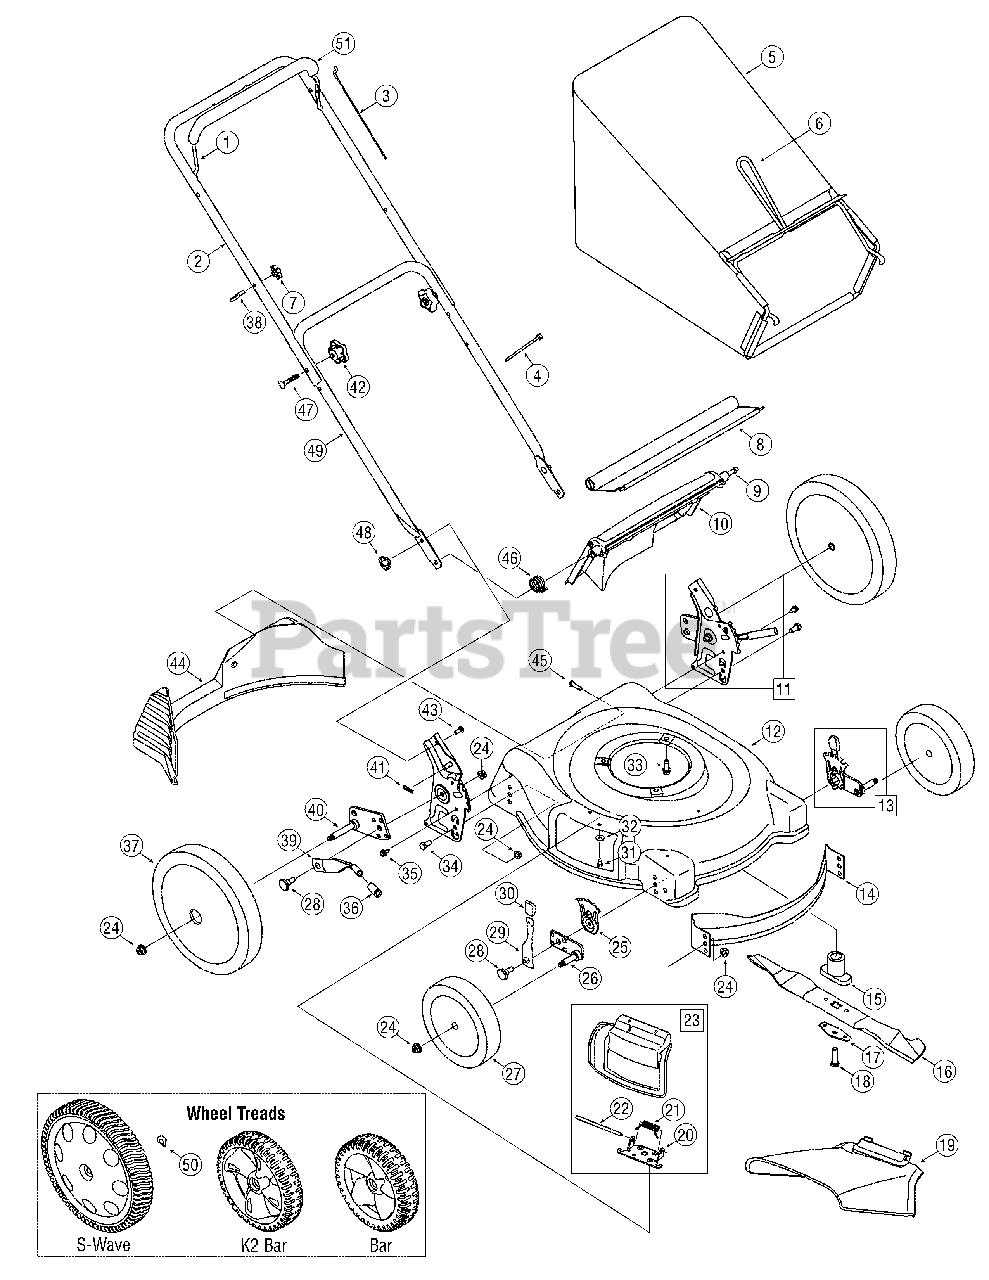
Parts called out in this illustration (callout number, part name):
3	Control Cable, 40"
4	Cable Tie
5	Grass Bag Assembly
7	Handle Knob
8	Trail shield
10	Rear Discharge Door
11	Rear Handle Bracket Assy. - LH
11	Rear Handle Bracket Assy. - RH
13	Front Height Adj. Assy-RH
14	Front Baffle
15	Blade Adapter
16	21-inch Mulching Blade
17	Bell Blade Support
18	Hex Screw, 3/8-24 x 2.5
19	Side Discharge Chute
20	Deflector Chute Adaptor
21	Torsion Spring
22	Hinge Pin
23	Hinged Mulch Plug Assembly
24	Flange Lock Nut 3/8-16
25	Height Adjustment Plate
26	Front Pivot Arm Assembly - RH
26	Front Pivot Arm Assembly - LH
27	Front Wheel, 8 x 2.125, S-Wave
28	Shoulder Screw, .5D x .434
29	Front Spring Lever
30	Height Adjust Knob
31	TT Screw, 1/4-20 x .500
32	Bell Washer
33	TT Screw, 3/8-16 x 1.0
34	Hex Screw, 3/8-16 x .75
35	TT Screw, 1/4-20 x .625
36	Foam Grip
37	Rear Wheel, 12 x 2.125, S-Wave
39	Rear Hi-Wheel Spring Lever
40	Rear Pivot Arm Assy - RH
40	Rear Pivot Arm Assy - LH
41	Hairpin Clip
42	Star Knob
43	Carriage Bolt ,1/4-20 x .75
44	Rear Baffle
45	Screw HL, 1/4-15 x 1.00
46	Torsion Spring - RH
47	Carriage Bolt, 5/16-18 x 2
48	Wing Nut
50	Spring Washer
51	Deluxe Red Bail Cover
